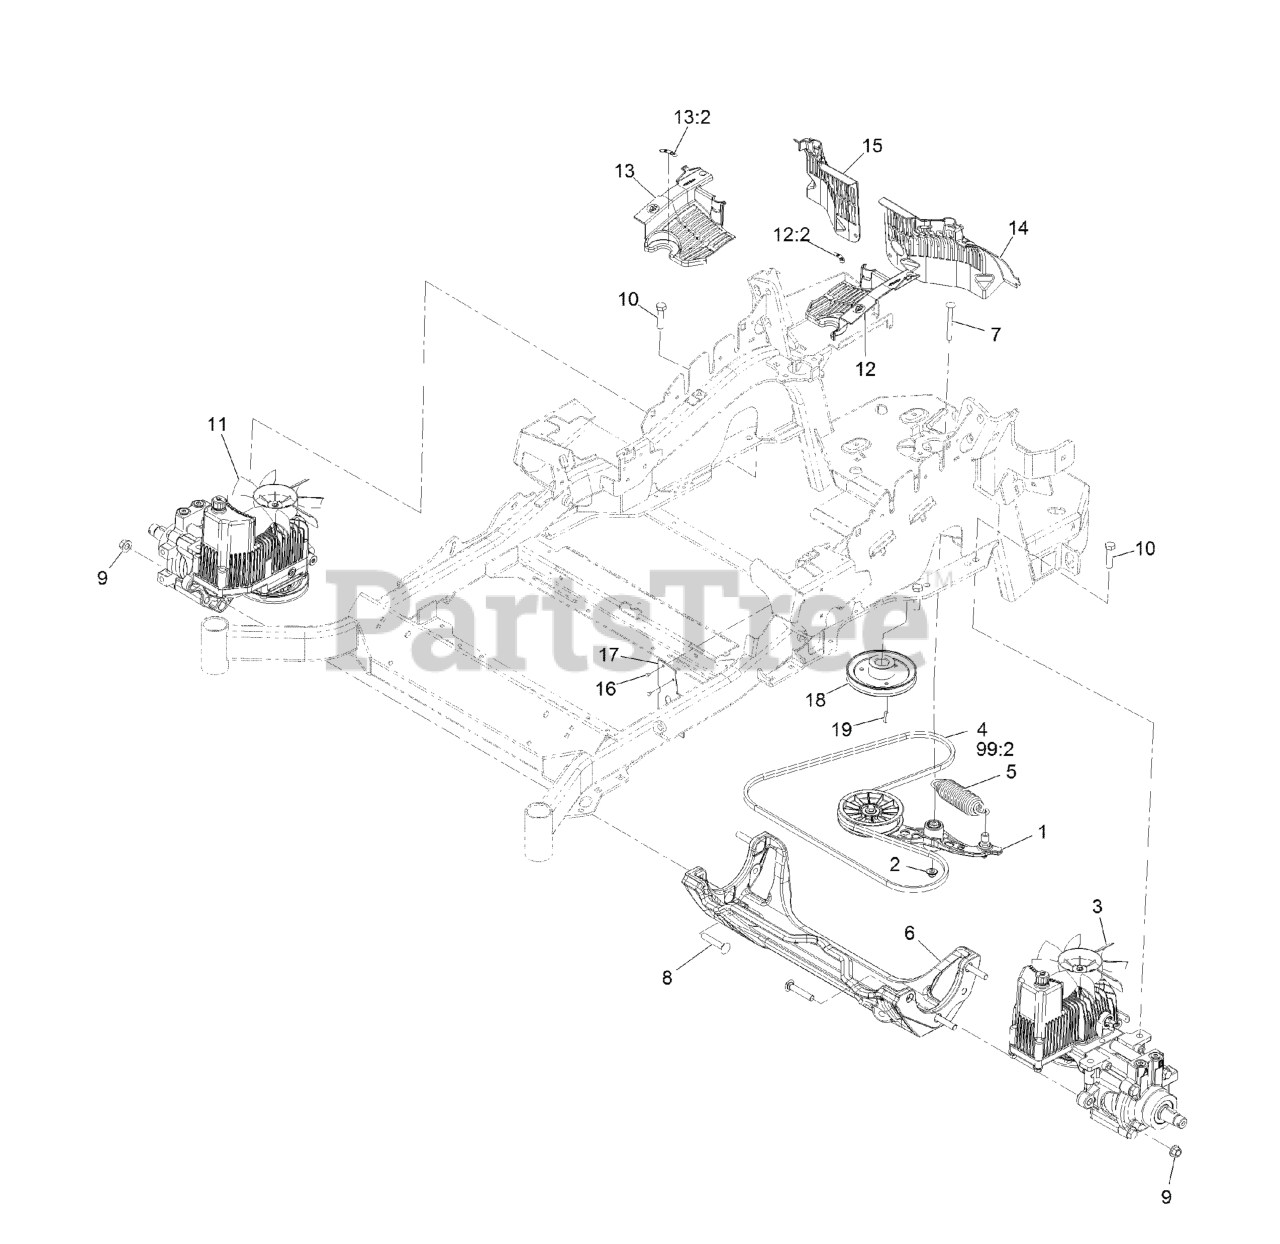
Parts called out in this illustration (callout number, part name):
1	PUMP IDLER ASM
2	Nut-Nyloc 3/8-16 Flg
3	LH HYDRO ASM (12CC W/ SHO
4	BELT
5	SPRING-EXTENSION
6	CRADLE-HYDRO
7	BOLT-SHOULDER, CARRIAGE 3/8-16 X 3 1/2
8	SCREW-CARR
9	Nut-Lock 1/2-13
10	SCREW-HH
11	RH HYDRO ASM (12CC W/ SHO
12	LH HYDRO GUARD ASM
12:2	DECAL-OIL, HYDRO
13	RH HYDRO GUARD ASM
13:2	DECAL-OIL, HYDRO
14	GUARD-HYDRO, REAR (LH)
15	GUARD-HYDRO, REAR (RH)
16	RIVET-POP
17	DEFLECTOR-AIR FLOW
18	SHEAVE
99:2	BELT
